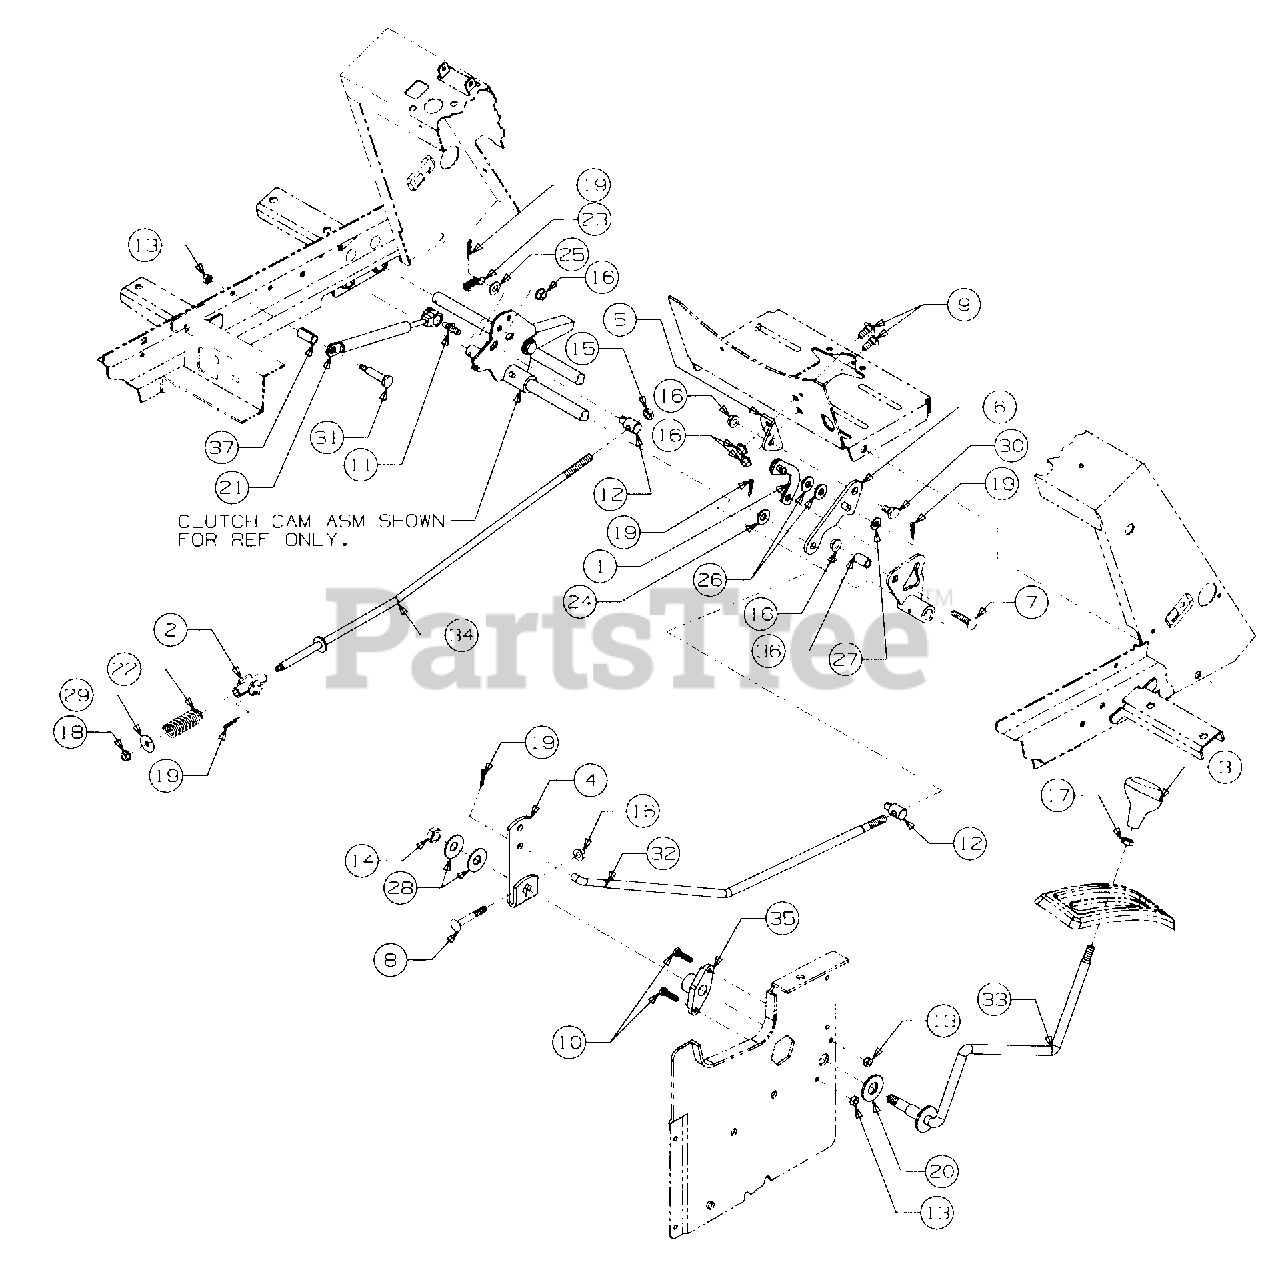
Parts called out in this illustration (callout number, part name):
1	Bracket Assy, Cruise Return
2	Pivot Assy, Sleeve
3	Knob, Shifter
4	Bracket, Gear Shift
7	Bolt, Carriage, 5/16-1 8 x 1.50 Lg
8	Bolt, Carriage, 5/16-18 x 2.25 Lg GR5
9	Bolt, Carriage, 5/16-18 x .75 Lg
10	Screw, Hex Cap, 1/4-20 x 1.0 Lg
11	Screw, Ball, 5/16-18
12	Ferrule, Adjustment
13	Nut, Hex Sems, 1/4-20
14	Nut, Hex Jam Lock, 1/2-20
15	Hex Jam, 3/8-24 GR5 Nut,
16	Nut, Hex Flange Top Lock, 5/16-18
17	Nut, Hex Jam, 3/8-16 GR5
18	Nut, Hex Flange Lock, 1/4-20
19	Pin, Internal Cotter, 5/16 Dia x 1.12 Lg
20	Washer, Friction
21	Cylinder, Damper
22	Spring, Compression, .63 ID x 2.0 Lg
23	Spring, Extension, .38 OD x 1.44 Lg
24	Washer, Bell, .380 X.88 x .062 Thk
25	Washer, Flat, .406 x .75 x .063 Thk
26	Washer, Flat, .375 x .870 x .090 Thk
27	Washer, Flat, 5/16
28	Washer, Bell
29	Washer, Flat, .265 x 1.0 x .030 Thk Hdn
30	Bolt, Shoulder, .437 Dia x .180 Lg
31	Bolt, Shoulder, .374 Dia x 1.375 Lg
32	Rod, Hydro Stop
33	Lever, Cruise Control
34	Rod, Hydro Adjustment
35	Bushing, Control Lever
36	Spacer, .3776 ID x .500 OD x .830 Lg
37	Spacer, Split Tubing, .375 ID x .520 OD x 1.04 Lg
